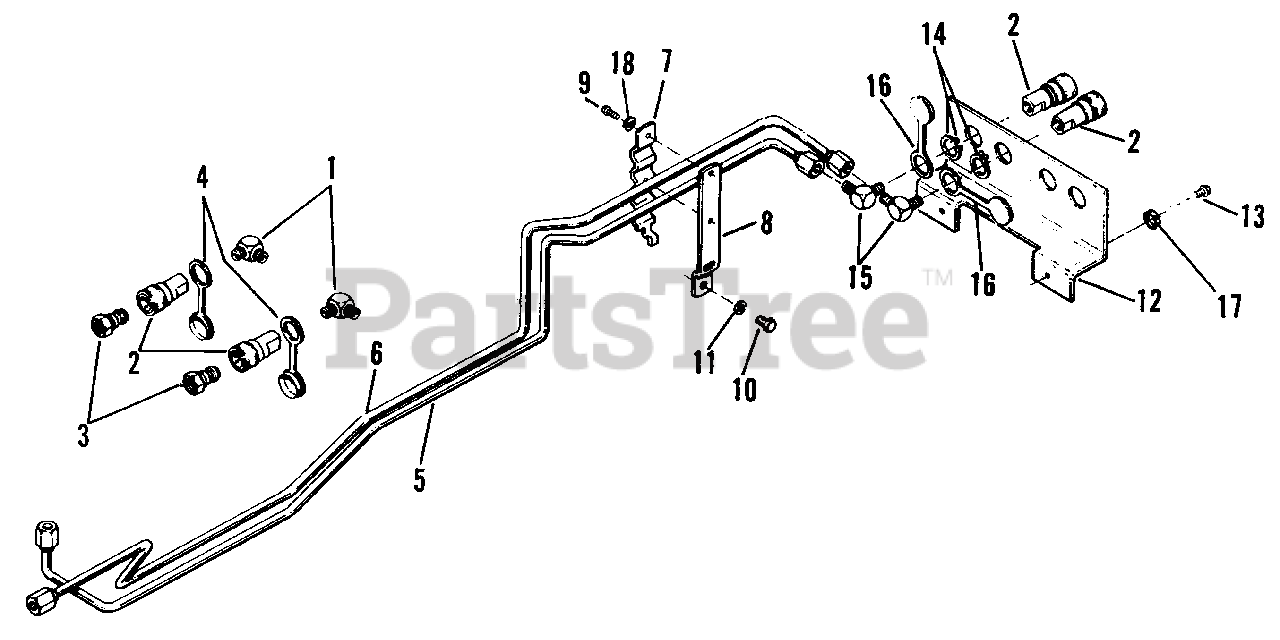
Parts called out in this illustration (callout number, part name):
1	Pipe Elbow
2	Body Assembly
4	Plastic Plug
5	Tube Assembly
6	Tube Assembly
9	Thread Forming Screw 1/4"-20 x 5/8"
10	Hex Capscrew, 3/8"-16 x 5/8"
11	Lock Washer, 3/8"
12	Mounting Plate
13	Thread Forming Screw 1/4"-20 x 1/2"
14	Retaining Ring
16	Plastic Plug
17	Lock Washer, 1/4
